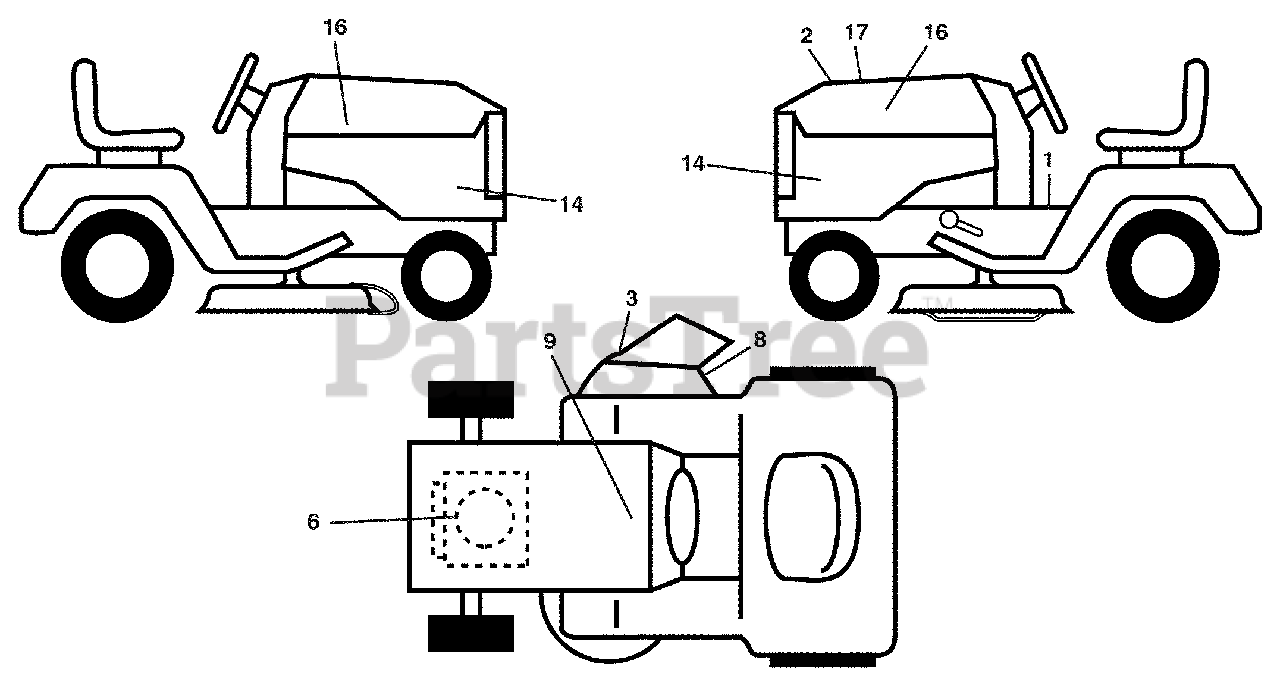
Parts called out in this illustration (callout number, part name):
1	Decal, Operator's
2	Decal, Hood Insert
3	Decal, Warning
6	Decal, Eng. HP
8	Decal, Mower Sch.
9	Decal, Battery Dnge/Poi
14	Decal, Panel Side
16	Decal, Hood Logo
17	Decal, Replacement
